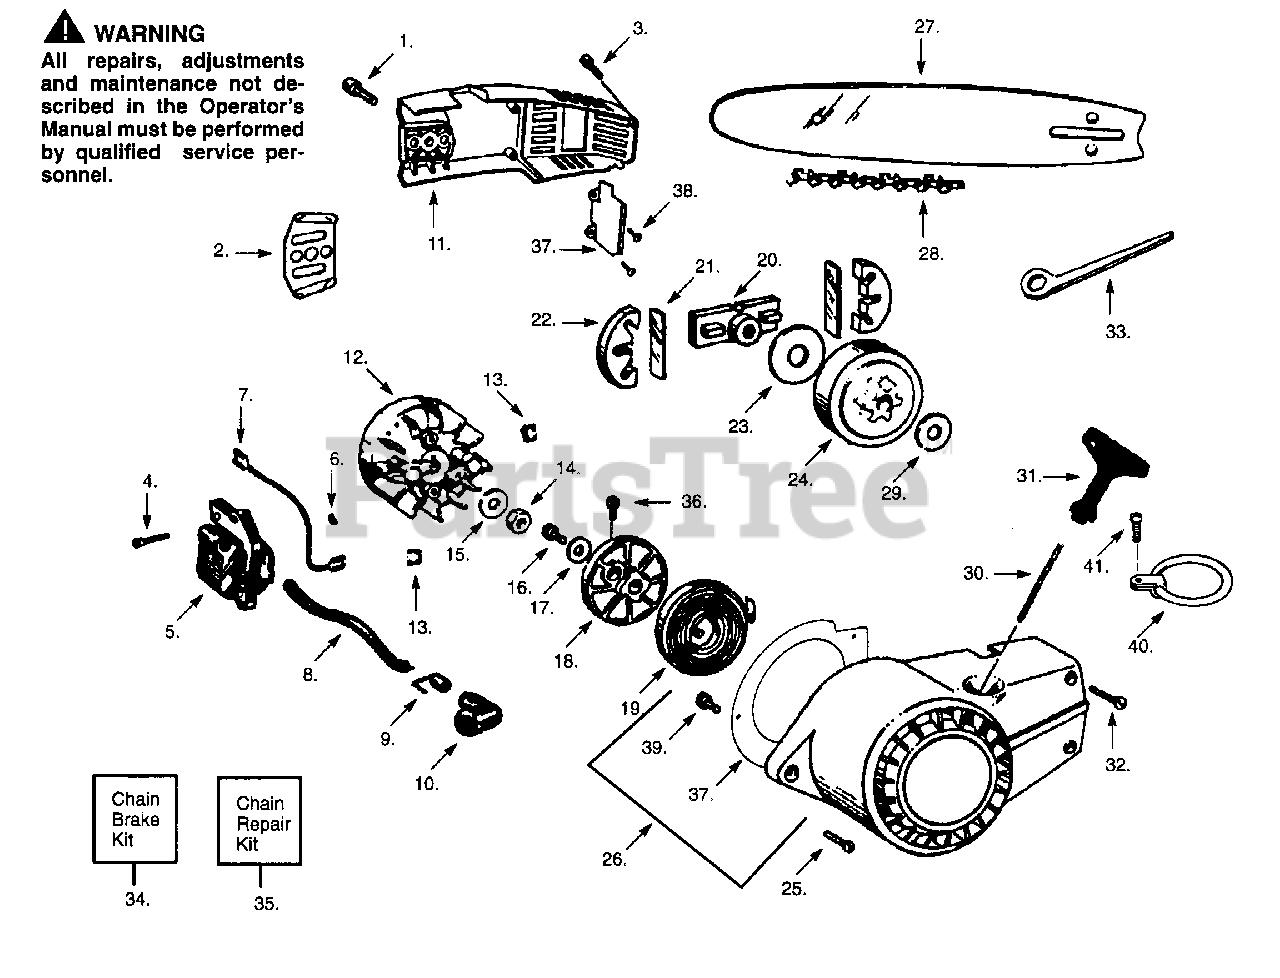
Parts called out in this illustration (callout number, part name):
2	Guide Plate
4	Screw
5	Ignition Module
6	Flywheel Key
7	Lead Stop Switch
8	High Tension Lead (Bulk No. 8141)
9	Connector Spring Plug
10	Spark Plug Boot
11	Bar Clamp
12	Flywheel Ass'y.
13	Starter Dog Spring
18	Starter Pulley
19	Starter Spring
20	Clutch Spider
21	Clutch Springs
22	Clutch Shoes
23	Clutch Plate
24	Drum & Sprocket Ass'y.
26	Fan Housing
27	Bar - 16" SN
28	Chain - 16" (P101S-56)
29	Clutch Washer
30	Rope Kit
31	Starter Handle
33	Bar Wrench
35	Chain Repair Kit
40	Rope Ring Kit
